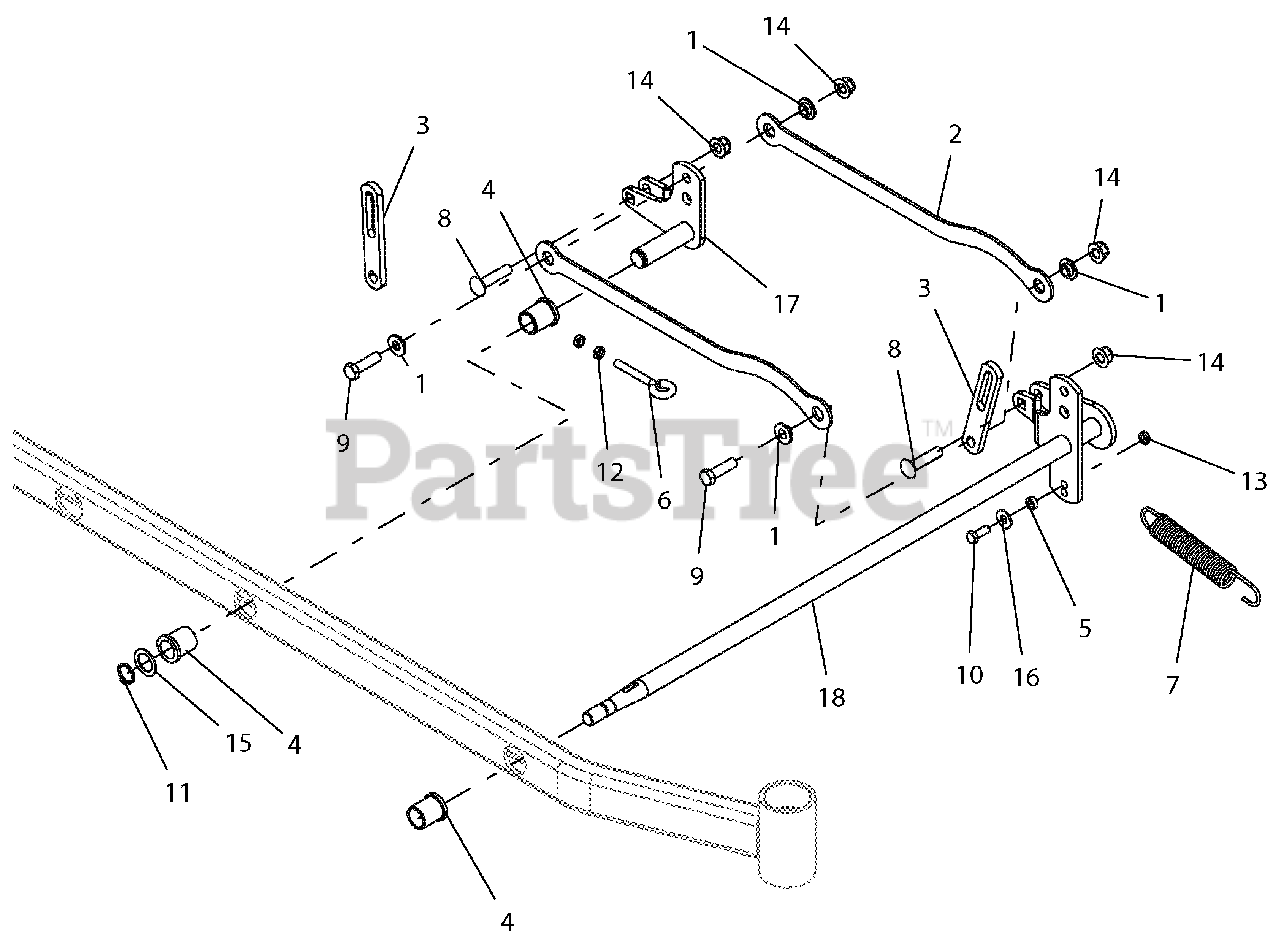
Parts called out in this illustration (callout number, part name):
1	BSHG, FLANGE .515X.750X.31X1.12
2	LINK, LIFT - BLK
3	LINK, DECK LIFT - LONG
4	BSHG-FLG 1.00X1.25X1.5X1.5
5	BSHG, SLV .377X.624X.235
6	BOLT, EYE .375-16
7	SPRG, TENSION .162 X 1.250 X 8.250
8	BLT-RDHDSQNK .50-13X2.25 G5 Y
9	BLT-HEX .50-13X1.75 GR5 YWZC
10	BLT-HEX .38-16X1.00 GR5 YWZC
11	RG-RTNG-EXT 1.00X.078
12	NUT, JAM .375-16 YWZC
13	@NUT-LK-CTR-JAM .375-16 YWZC
14	NUT-LK-NYL-FLG .50-13 YWZC
15	WSHR-FL-STL 1.010X1.505X.062 YWZC
16	WSHR-FL-STL.438X1.00X.083 YWZC
17	WLDMT, LH REAR DECK LIFT
18	WLDMT, PT200 FRONT LH DECK LIFT ARM-BLACK
